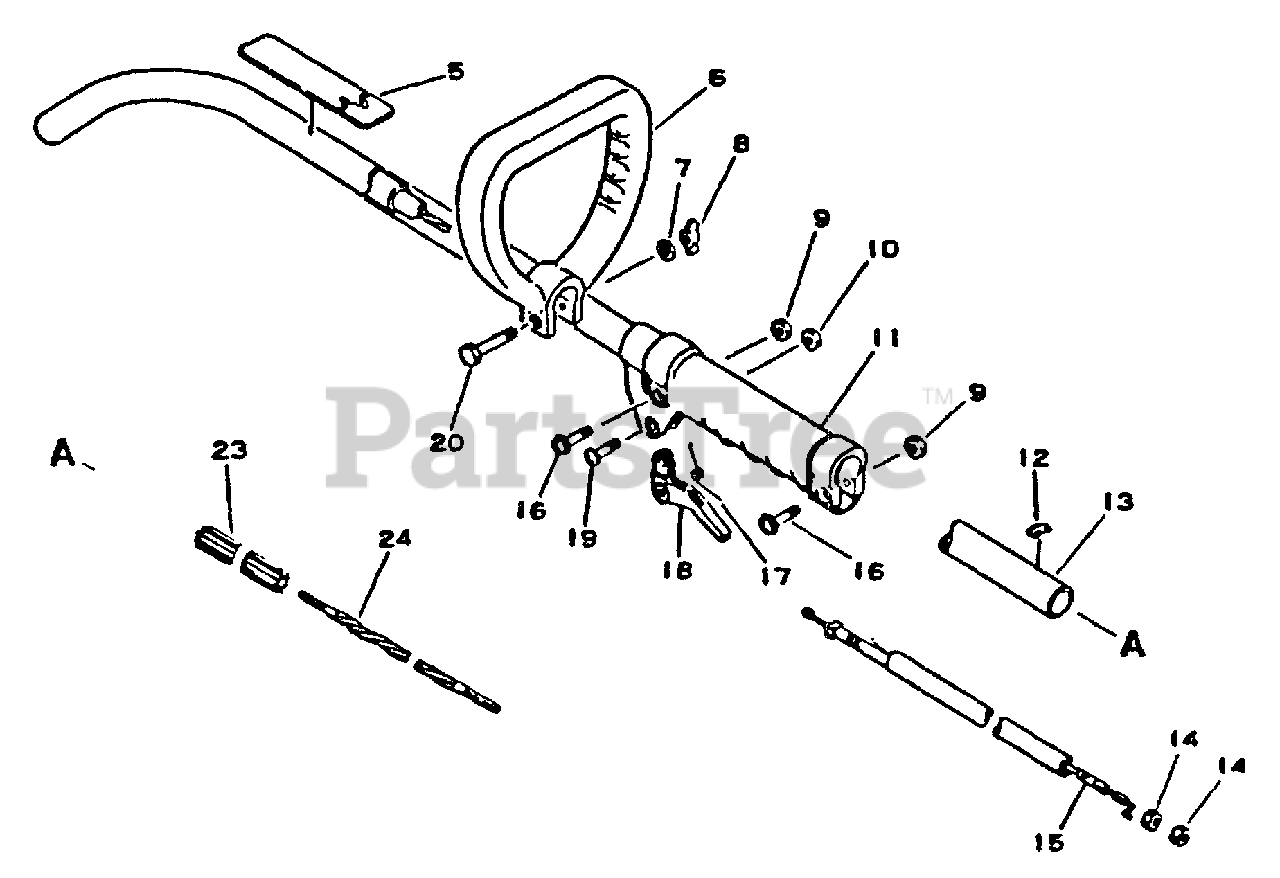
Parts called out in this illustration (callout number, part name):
5	LABEL - CAUTION
6	HANDLE - FRONT
7	WASHER - 6
8	WINGNUT - 6
10	LOCKNUT - 5
11	GRIP, HANDLE
12	LABEL - ALIGNMENT
13	MAIN PIPE ASSY
15	CABLE, THROTTLE
16	SCREW - 5X25
17	SPRING, TRIGGER
18	TRIGGER, THROTTLE
19	SCREW - 5X30
20	BOLT - 6X40
23	LINER - FLEXIBLE
24	DRIVESHAFT - FLEXIBLE
C5	LABEL - CAUTION
